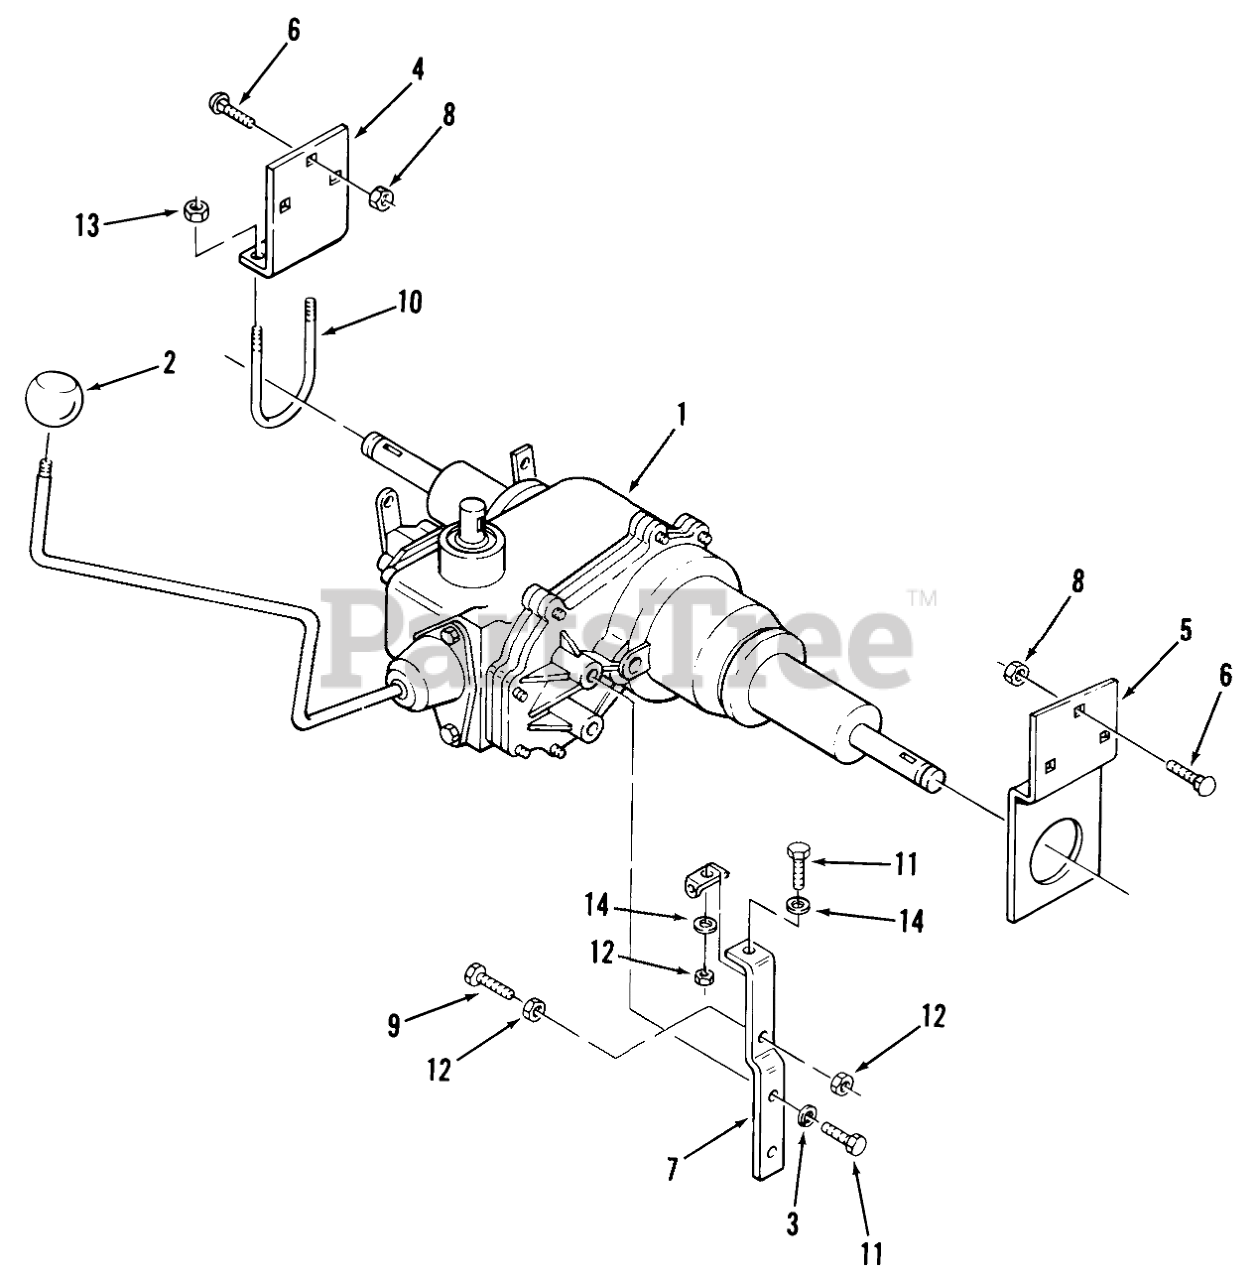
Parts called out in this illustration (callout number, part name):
1	Transmission-Peerless Mod. 601-001
2	SHIFT KNOB
3	Lockwasher
4	BRACKET-AXLE RH
5	BRACKET-AXLE LH
6	CARRIAGE BOLT -4
7	Bracket Trans. Mounting
8	Nut
9	Bolt 5/16-18 x 2
10	"U" Bolt Axle Mount
11	Bolt
12	Nut
13	Nut
14	WASHER 5/16 SAE
